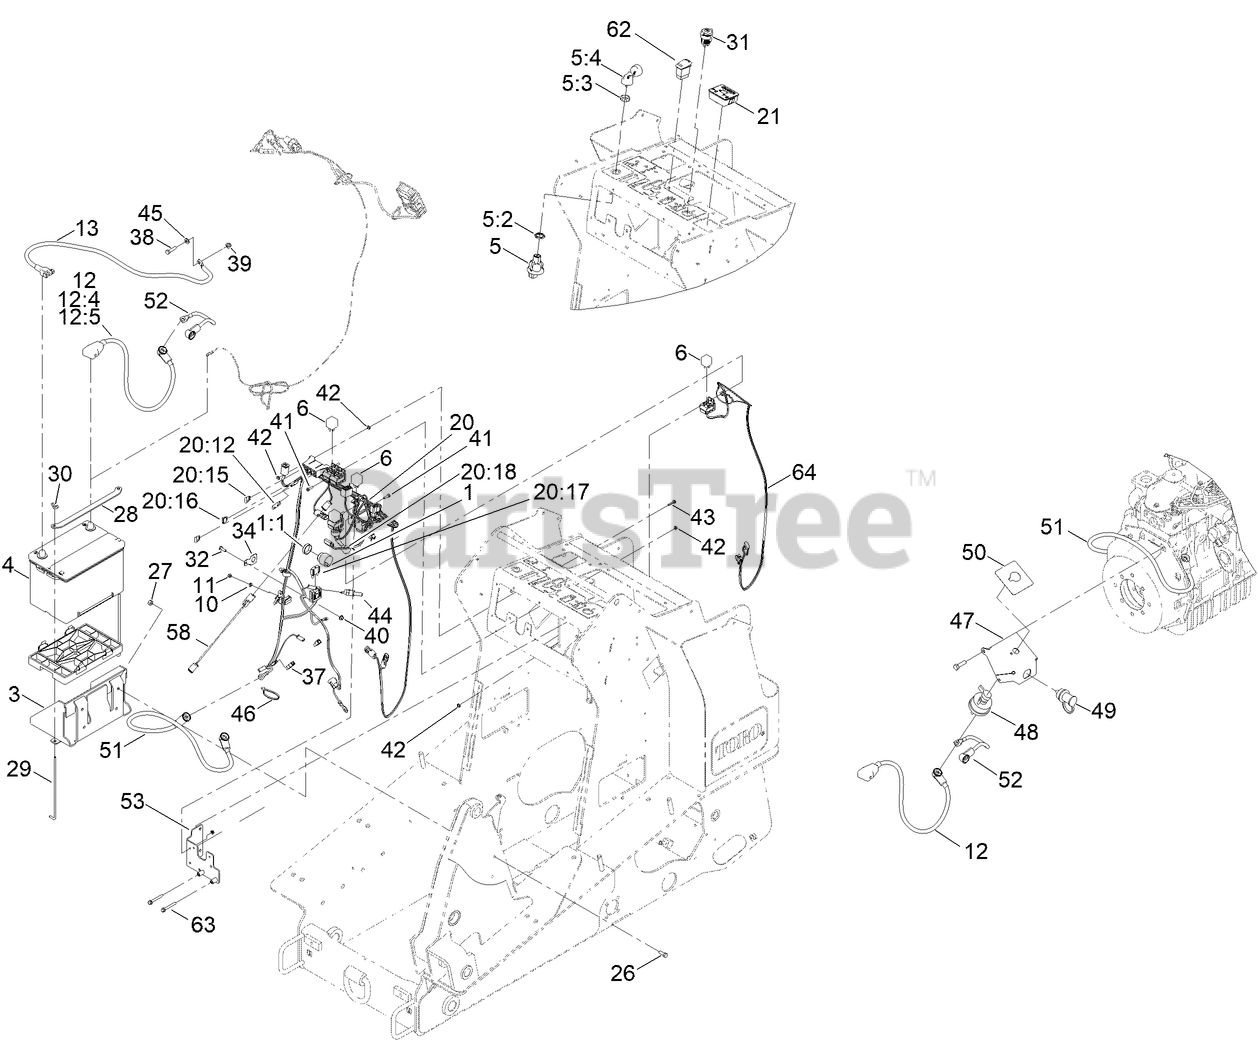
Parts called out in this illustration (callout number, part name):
1	AUDIO ALARM ASM
1:1	NUT-PLASTIC, KNURLED
3	TRAY-BATTERY
4	BATTERY
5	IGNITION SWITCH ASM
5:2	NUT-HEX
5:3	NUT-FACE
5:4	SET-KEY, IGNITION
10	WASHER-LOCK, SPRING
11	NUT-HEX
12	CABLE-BATTERY, POS ASM
12:4	BOLT-BATTERY CLAMP, 5/16-18 UNC
12:5	NUT-CLAMP, BATTERY
13	CABLE-NEGATIVE
20	HARNESS-WIRE, TX1000
20:15	FUSE-BLADE, 10 AMP
20:16	FUSE-BLADE, 15 AMP
20:17	FUSE-BLADE, 50 AMP
20:18	CAP-PLUG
21	MODULE-HOUR METER
26	SCREW-HH
27	NUT-LOCK, NI
28	STRAP-HOLD DOWN, BATTERY
29	ROD-HOLD DOWN, BATTERY
30	NUT-WING
31	RECEPTACLE-12V
32	SCREW-HH
34	CLIP-FUSE
37	HARNESS-LINK, FUSIBLE
38	SCREW-HH
39	NUT-HF, NI
40	NUT-HF
41	SCREW-HWH
42	NUT-KEPS
43	SCREW-HWHTF
44	SWITCH-TEMP
45	WASHER-PLAIN
46	TIE-CABLE
47	MOUNT-REMOTE TERMINAL
48	SWITCH-DISCONNECT, MASTER
49	STUD-JUMPER, POSITIVE
50	DECAL-BATTERY DISCONNECT
51	CABLE-BATTERY, POSITIVE
52	CABLE-BATTERY, POSITIVE
58	HARNESS-WIRE
62	SWITCH-INTERMITTENT
63	SCREW-HHF
64	HARNESS-WIRE, AUX HOLD
